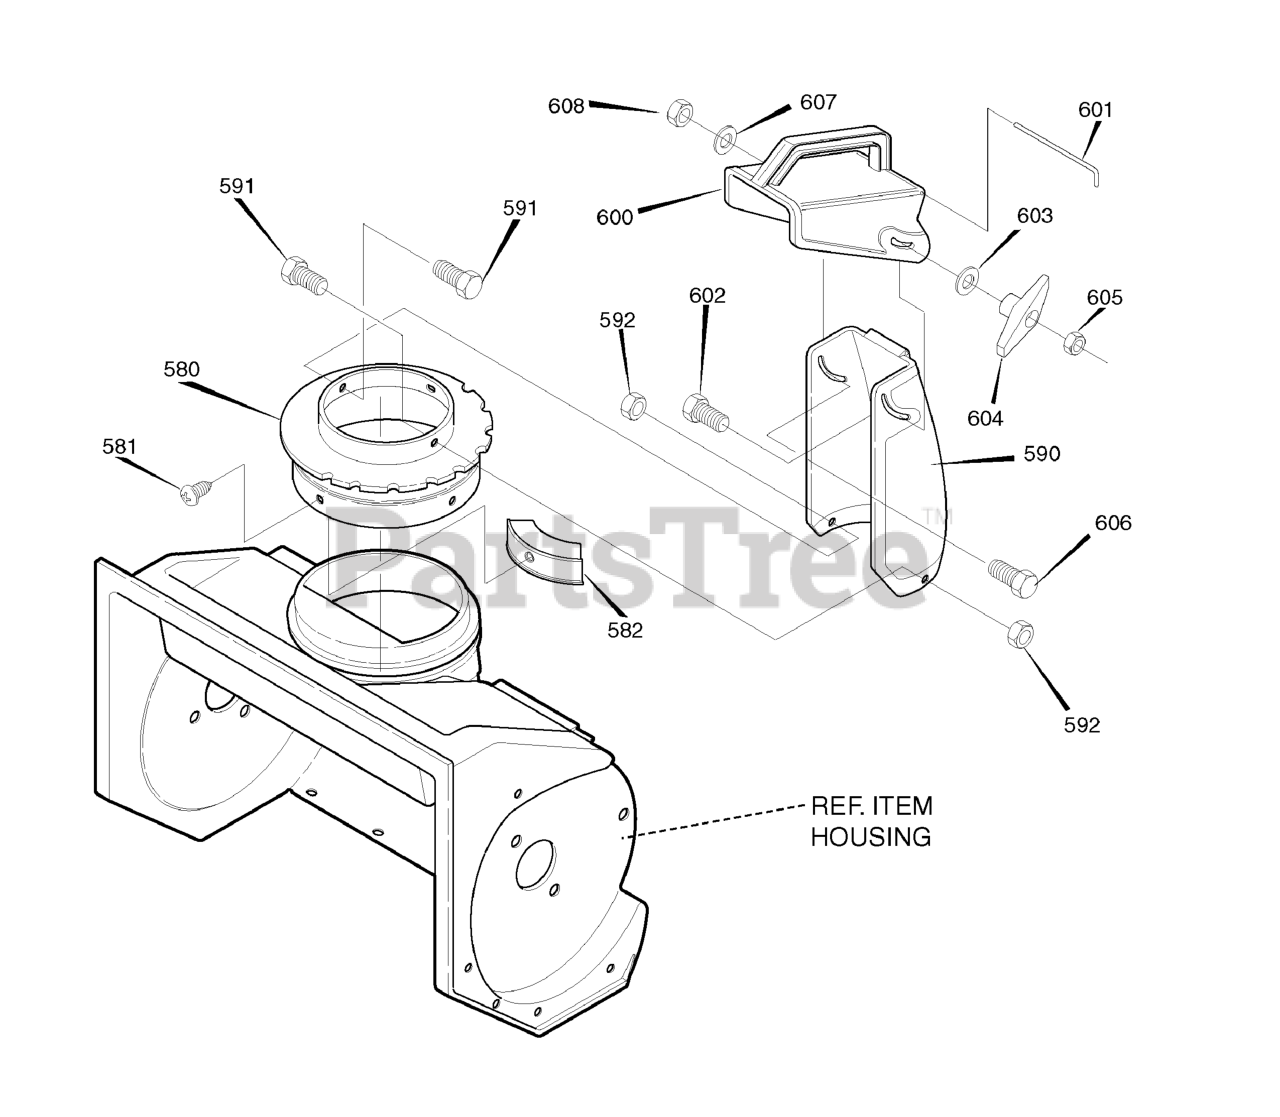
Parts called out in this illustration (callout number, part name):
580	RING, CHUTE
581	SCREW, 1/4-20 x .50
582	GUIDE, CHUTE
590	LOWER CHUTE
591	SCREW, 1/4-20 x .50
592	NUT, 1/4-20
600	UPPER CHUTE
601	WIRE HINGE
602	BOLT, 5/16-18 x 1.25
603	FLATWASHER
605	NUT, 5/16-18
606	SCREW, 5/16-18 x 0.75 SL
607	FLATWASHER
608	NUT, 5/16-18
